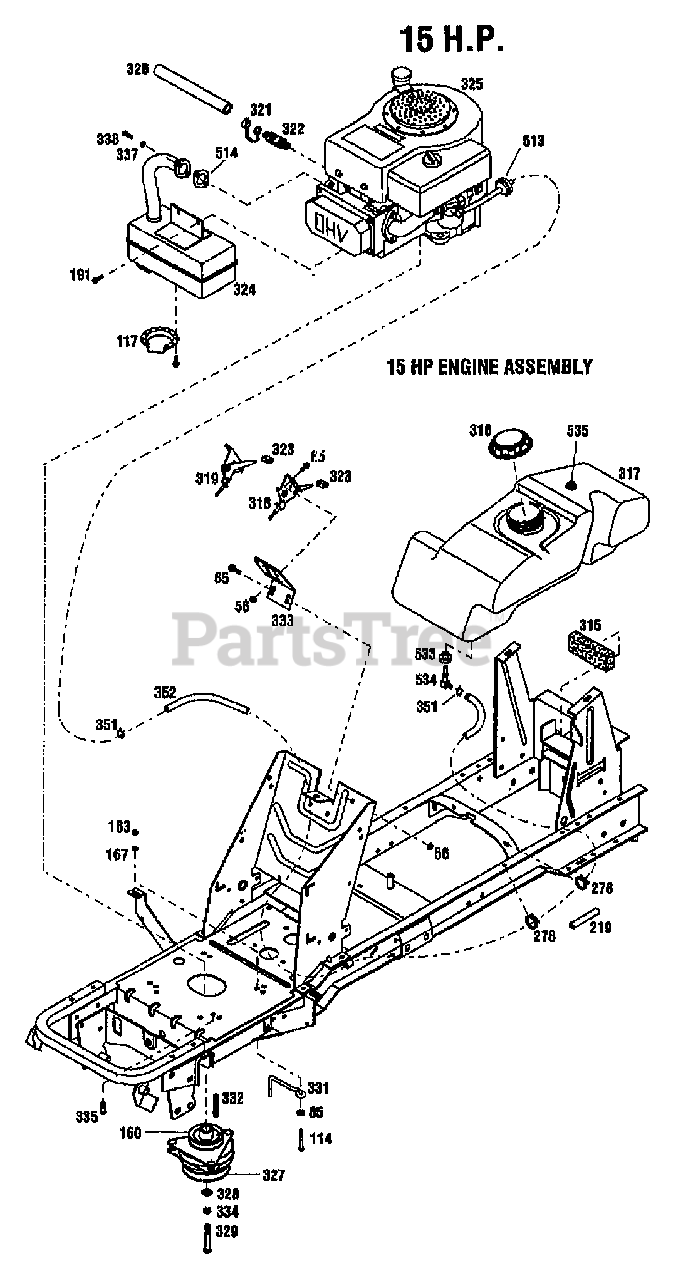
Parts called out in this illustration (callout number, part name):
56	NUT-HF/LK 1/4-20 ZP
65	SCR-HH 1/4-20X.625
85	WASHER-FLAT 3/8 SAE
114	SCR-THRD FRM 3/8-16X1.50
117	DEFLECTOR-MUFFLER
160	PULLEY-ENGINE
163	NUT-HEX 3/8-16 ZP
167	WASHER-LK .375 @ DEPL
191	SCR-FLANGE 1/4-20X3/4 GR5
278	TIE-CABLE NYLON BLACK
315	PAD-FUEL TANK
316	CAP-FUEL
317	TANK-FUEL
318	CONTROL-THROTTLE
319	CONTROL-CHOKE
320	HOSE
321	CAP-OIL DRAIN
322	ASSM-OIL VALVE
324	MUFFLER
325	ENGINE B&S #2BN707-0112-01
327	CLUTCH-ELECTRIC
328	WASHER-SPEC 1.42X.468X.25 ZP
329	SCR-HH 7/16-20X3.00
331	CLUTCH-RETAINER
332	KEY-.25 SQ X 2.5
333	BRKT-MOUNTING CONTROL
334	WASHER-LK .438 ZP
335	SCR-HH 3/8-16X1.0 THDFM
337	WASHER-LOCK
338	SCR-HXSKT 5/16-18X.75 BO
351	CLAMP-HOSE
352	LINE-FUEL
513	FILTER-FUEL
514	MUFFLER GASKET
533	BUSHING-RUBBER
534	ELBOW-90 DEG (FUEL LINE)
535	VENT-FUEL TANK
